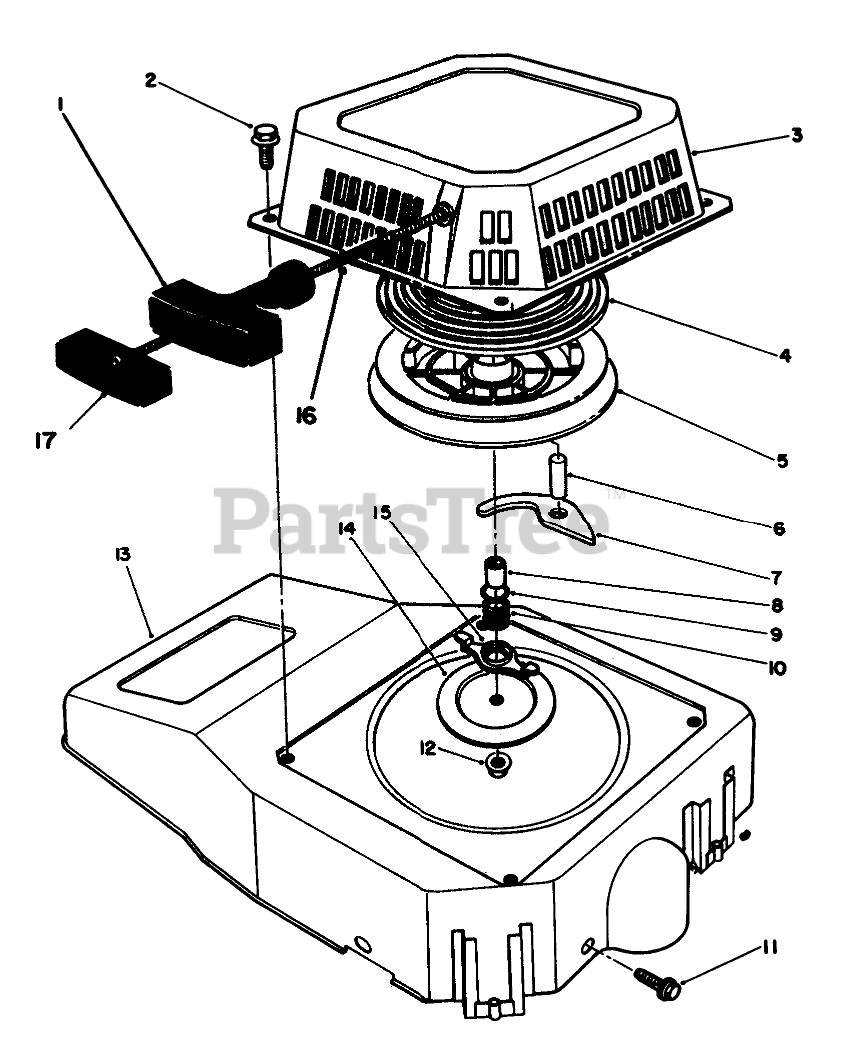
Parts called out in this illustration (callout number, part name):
2	SCREW-HHF
3	Case-Recoil
4	SPRING
8	Spacer
9	WASHER
10	Spring-Friction
13	SHROUD
14	PLATE
15	Guide-Paw
16	ROPE-STARTER
17	RETAINER HANDLE
